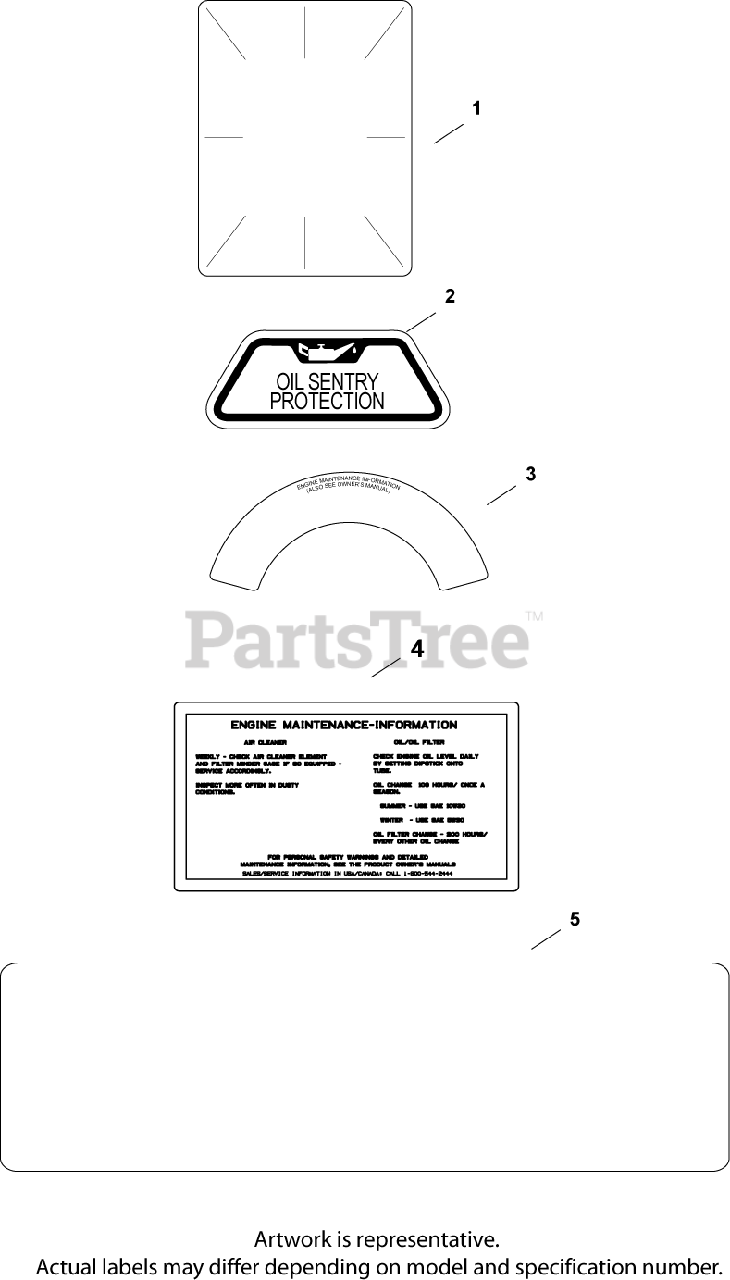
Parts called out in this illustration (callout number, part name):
1	DECAL, CLEAR LAMINATE USE 25 113 70-S
2	DECAL, OIL SENTRY - (#DSC)
3	DECAL, ENGINE MAINTENANCE-DISC.
4	DECAL, OIL COOLER - (#DSC)
5	DECAL, 23 HP - DISCONTINUED
